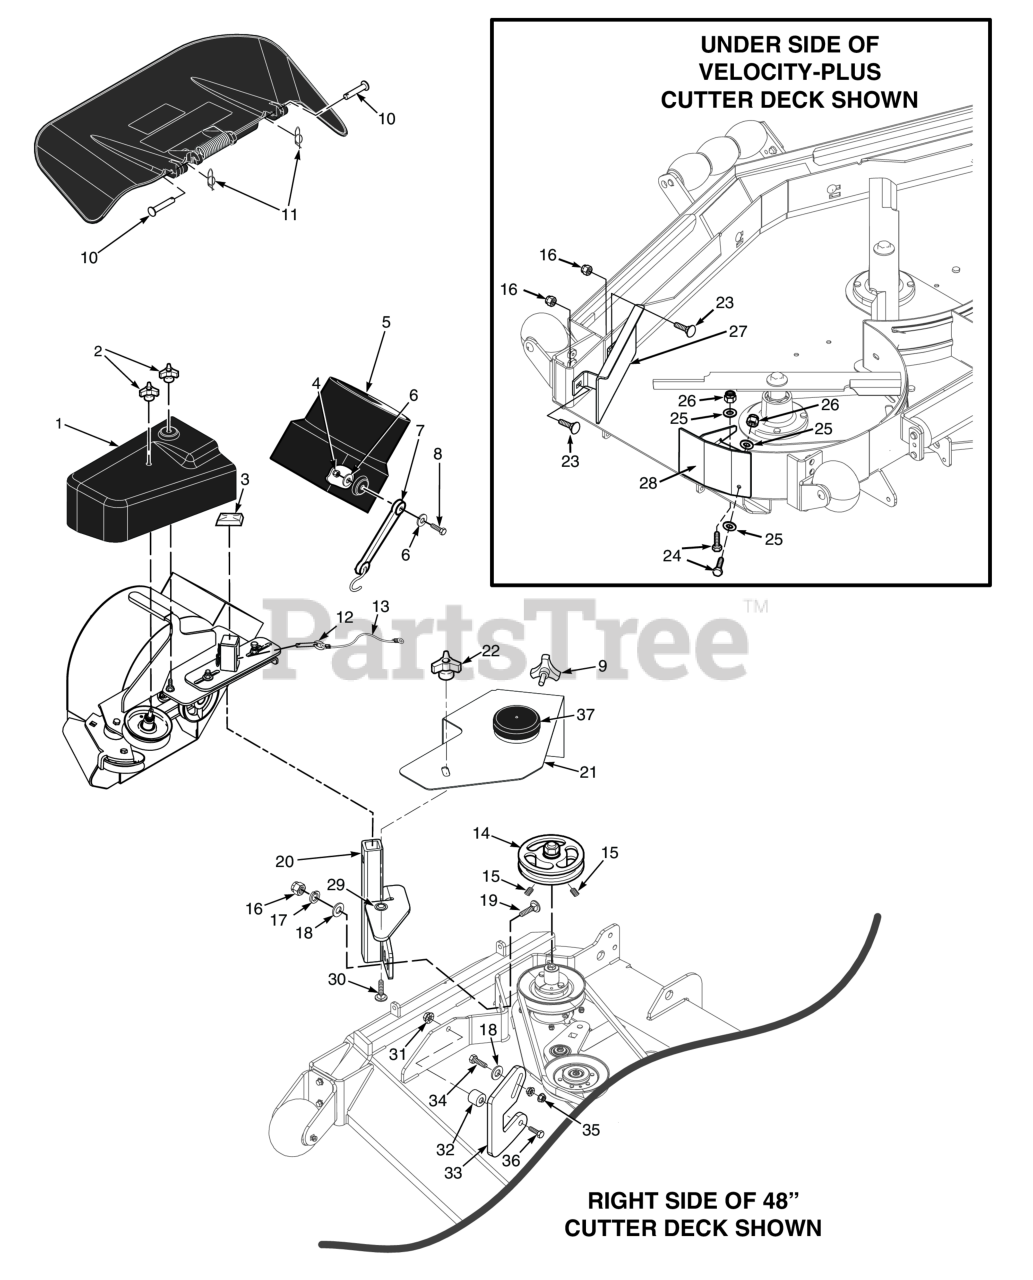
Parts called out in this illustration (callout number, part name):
1	Belt Cover, 48"
2	Wing Nut, 3/8-16 (Small) Top side
3	Cap, Square Vinyl
4	HEX, NUT, ELASTIC STOP LOCK, 1/4-20
5	Adapter, Blower GC-STC,
6	Flatwasher, 1/4" (.312 x .750 x .065")
7	Rubber Strap 7-3/4"
8	SERR. FLG. HEX HEAD CAPSCREW, 5/16-18 X 3/4
9	Knob, w/stud 3/8-16 x 1-1/4"
10	Clevis Pin, 5/16 x 1-1/2"
11	Pin, Rue Cotter 5/16 Dia.
12	Pin, Ring 1/2 x 2-1/4"
13	Lanyard, Deck Height Pin
14	Pulley, 4.0" Dia. - 1.125" Bore, (STT-52 & STTII-52)
15	Setscrew, Hex Socket Knurl Cup Pt. 5/16 - 18 (nylock)
16	HEX NUT, ELASTIC STOP LOCK, 3/8-16
17	Lockwasher, 3/8" Spring, Kawasaki FX / FT & FT-EFI / B&S 32BV
18	Flatwasher, 3/8" Special (.391 x .938 x .105)
19	SHORT SQ. NECK CARRIAGE BOLT, 3/8-16 X 1-1/4"
20	Mounting Post Weldment, Blower, (61")
21	Belt Cover Assembly, w/Cap - 48"
22	Wing Nut, 3/8-16 (Small) Top side
23	Carriage Bolt, 3/8-16 x 1.0"
24	Bolt, Heax Head 5/16-18 x 1" (48V / 52V)
25	Flatwasher, 5/16-.375 x .875 x .083 (35BV & 37BV-EFI)
26	HEX NUT, ELASTIC STOP LOCK, 5/16-18
27	Baffle Weldment, 52V Deck
28	Baffle, Turbo 48" Deck
29	Nut, Push-On - 3/8" Dia.
30	Carriage Bolt, 3/8-16 x 1-1/4"
31	NUT, 3/8-16 SERRATED FLANGE HEX HEAD
32	Spacer (STCII48 & SCZ48)
33	Bracket (STCII48 & SCZ48)
34	Bolt, Hex Head 3/8-16 x 1-1/2" Grade 8 Black
35	NUT, 3/8-16 SERRATED FLANGE HEX HEAD
36	Bolt, Hex Head 3/8-16 x 1-3/4" (Kohler EFI)
